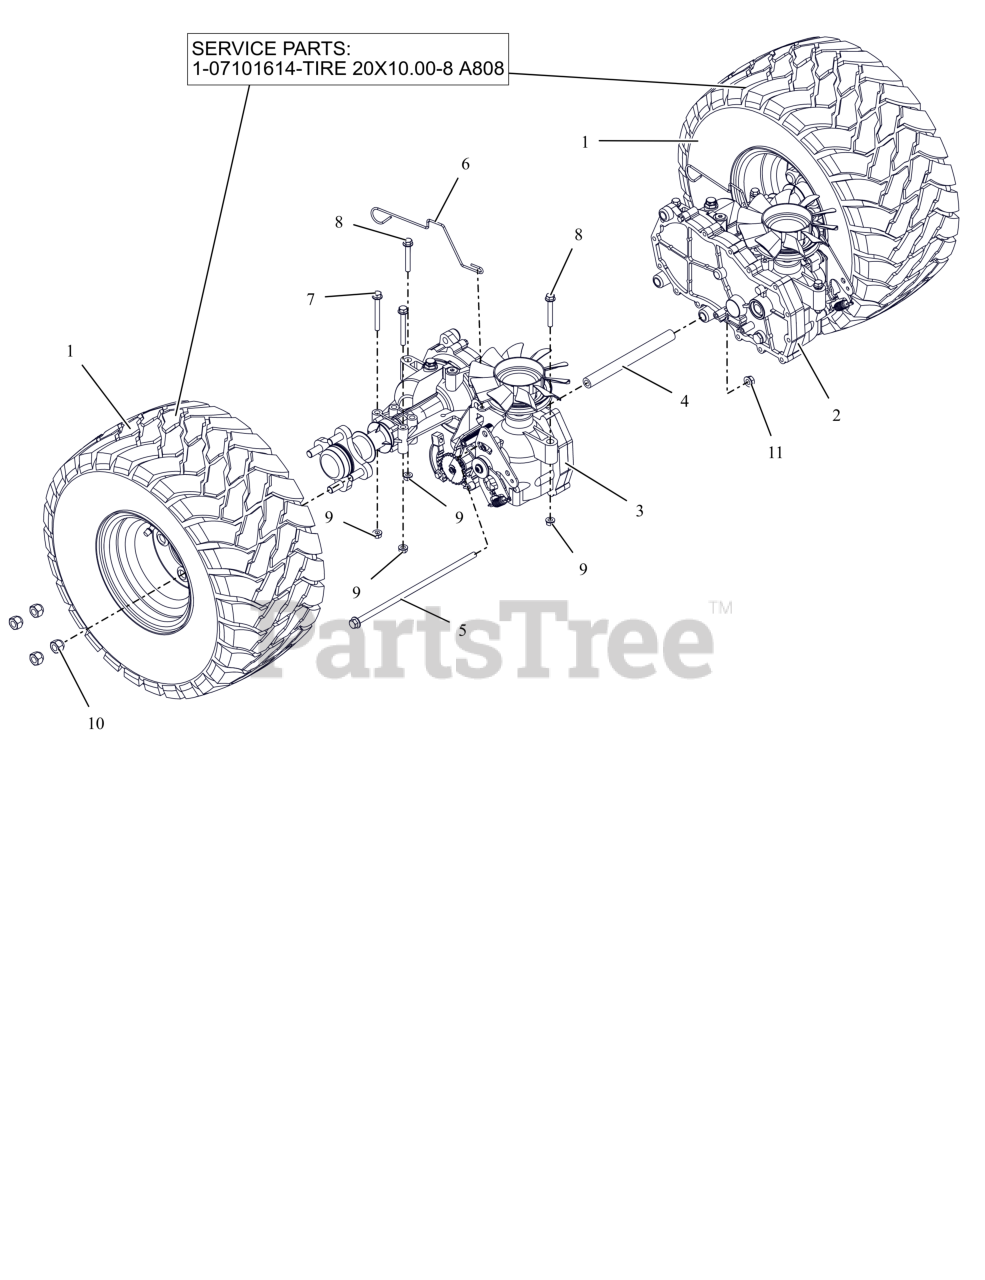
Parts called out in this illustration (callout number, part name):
1	ASM-WHL/TIRE 20X10.00-10 K505
1	TIRE 20X10.00-8 A808 TREAD
2	TRANSAXLE- SERVICEABLE EZT -LH
3	TRANSAXLE- SERVICEABLE EZT -RH
4	SPCR, TRANSAXLE .438 ID X .750 OD X 8.18 (BLACK)
5	BLT, HEX-FLG 0.375-16X11.5 GR5 ZC120
6	WIRE- DUMP VALVE LEVER
7	BLT,HEX-FLG .31-18X2.75 G5 ZCC
8	BLT,HEX-FLG .31-18X2.25 G5 ZCC
9	NUT,LK-CTR-FLG .31-18 GF ZCC
10	NUT, WHEEL .50-20 ZCC
11	NUT-LK-CTR-FLG .375-16 GF ZCC
